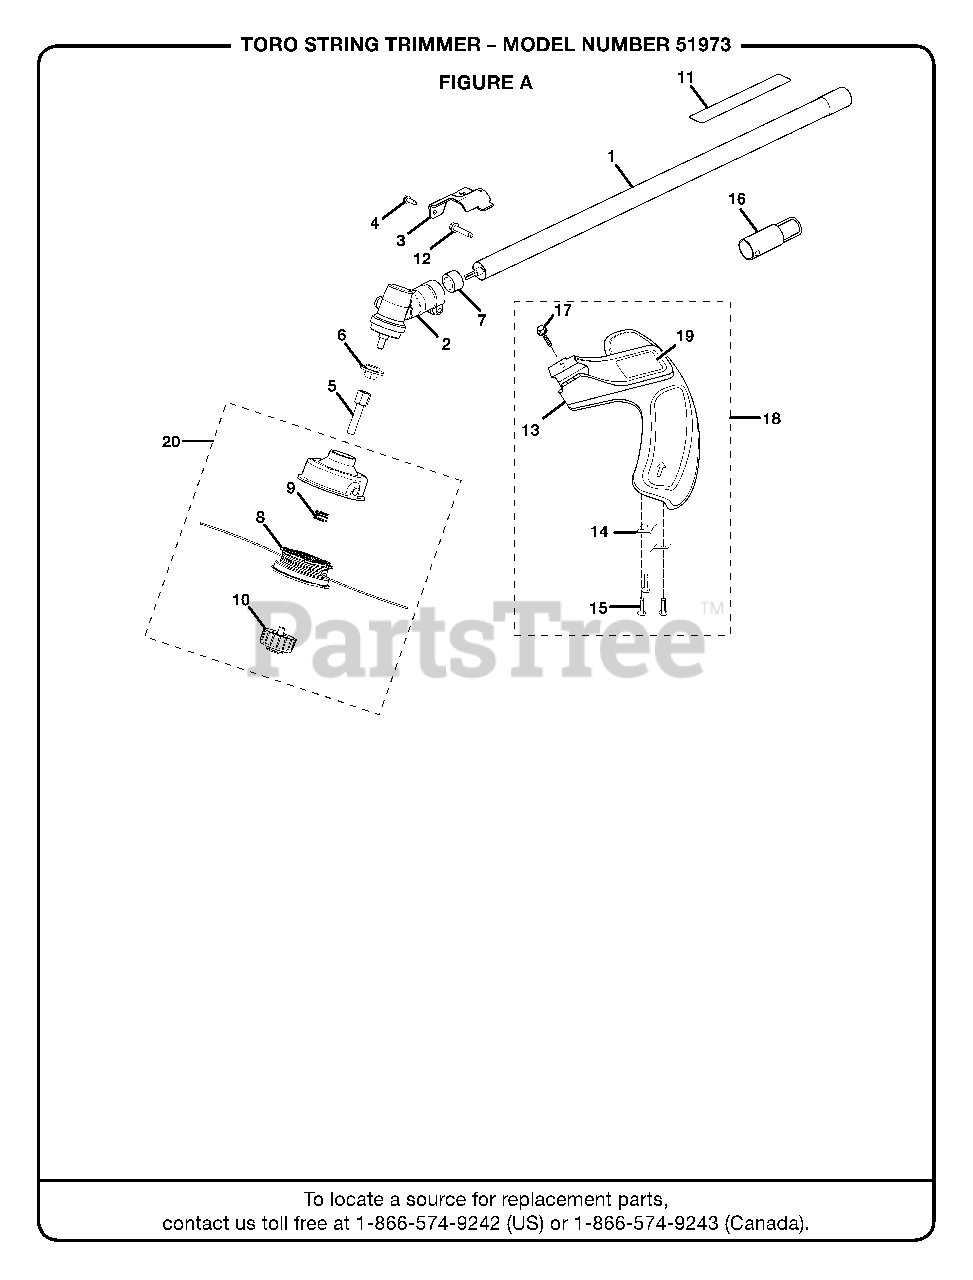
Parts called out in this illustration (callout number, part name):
1	STRAIGHT SHAFT ASSEMBLY
2	GEAR CASE ASSEMBLY
3	GRASS DEFLECTOR CLAMP
4	SCREW (#10-24 X 5/8 in. HEX WASHER HD.)
5	TRIMMER HEAD SHAFT ADAPTOR
6	FLANGED WASHER
8	SPOOL WITH LINE (.095)
9	COMPRESSION SPRING
10	RETAINING CAP, LEFT-HANDED THREAD
11	WARNING LABEL
12	SCREW (1/4-20 X 1-1/4 in.)
13	GRASS DEFLECTOR
14	LINE CUTTING BLADE
16	HANGER CAP
17	SCREW (#1/4-20 X 1-1/4 in. HEX WASHER HD.)
18	GRASS DEFLECTOR ASSEMBLY
19	GRASS DEFLECTOR LABEL
20	TRIMMER HEAD ASSEMBLY (.095)
